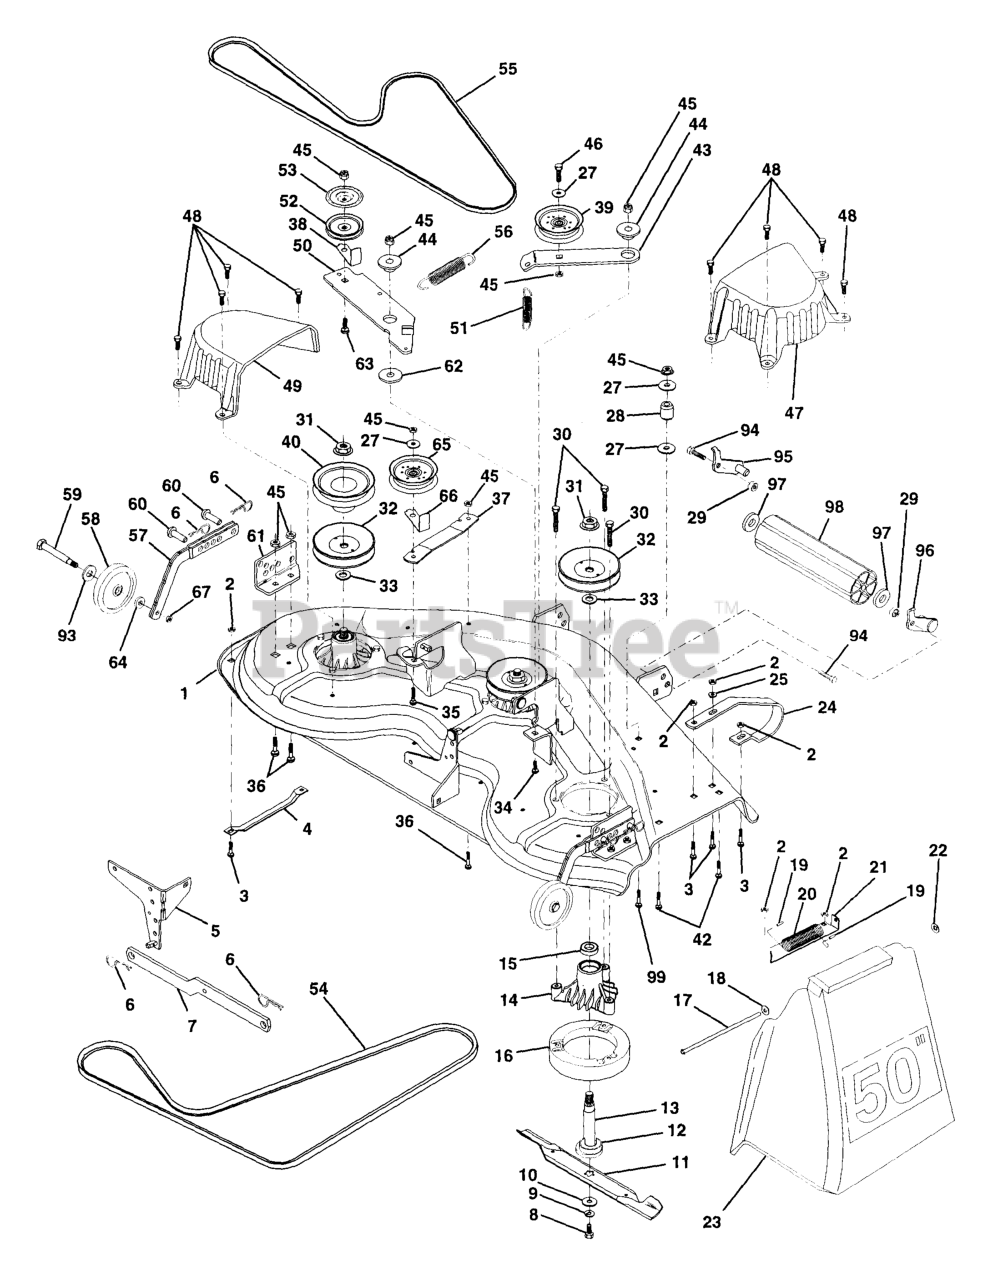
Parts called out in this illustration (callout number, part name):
1	DECK ASM MWR 50VT
2	LOCKNUT
3	BOLT.CARR.SQNK.5/16-18UNC.X3/4
4	RUNNER-LH M
5	BRACKET SWAY BAR
6	RETAINER-SPRNG RB
7	REAR SUSP ARM
8	BLADE BOLT
9	LOCKWASHER
10	WASHER.BLADE
11	BLADE.50".HI-LIFT
12	BEARING.BALL.#6204.(MANDREL)
13	SHAFT.ASM.W/BEARING
14	HOUSING.MANDREL.44/46" VENT
16	STRIPPER
17	ROD-HINGE T
18	Washer 11/32 x 5/8 x 16 Ga.
19	CAP-SLEEVE LT
20	SPRING TORSION
21	BRACKET, DEFLECTOR
22	NUT PUSH M
23	SHIELD.DEFLECTOR.MOWER.50"BLK.
25	WASHER M
27	WASHER
28	IDLER SPRING SPACER
29	NUT
30	SCREW
31	NUT
32	MANDREL PULLEY
33	WASHER
34	BOLT.3/8-14X1.25
35	BOLT
36	BOLT D
37	STIFFENER ARM
38	KEEPER
39	FLAT IDLER PULLEY
40	PULLEY.DRIVEN.44"
42	RP BOLT 5/16-18 X3/4 ZN/YEL GR
43	ARM.IDLER.SEC.44"
44	SPACER RETAINER
46	BOLT
47	COVER MANDRELL
48	SCREW.1/4-20X5/8
49	COVER.MANDREL.LH.44"
50	ARM.IDLER.PRIMARY
51	SPRING.SEC.44"VEN
52	PULLEY IDLER
53	SHIELD IDLER
54	V-BELT.PRMRY 46/50 VENT.BLK BK
55	BELT V SECONDARY
57	BAR.ASM.GUAGE.WHEEL
58	WHEEL.GAUGE.BLK.4.93
59	BOLT M
60	PIN.CLEVIS
61	BRACKET.GUAGE.WHEEL
62	HARDENED WASHER
63	BOLT.3/8-16X1.50
64	WASHER.5/16.FLAT.STE.STD.
65	IDLER-FLAT T
66	KEEPER
67	LOCKNUT
93	Washer 17/32 x 15/16 x 12 Ga.
94	BOLT
95	BRACKET LH (A)
96	BRACKET RH (B)
97	Washer 17/32 x 7/8 x 16 Ga.
98	NOSE ROLLER
